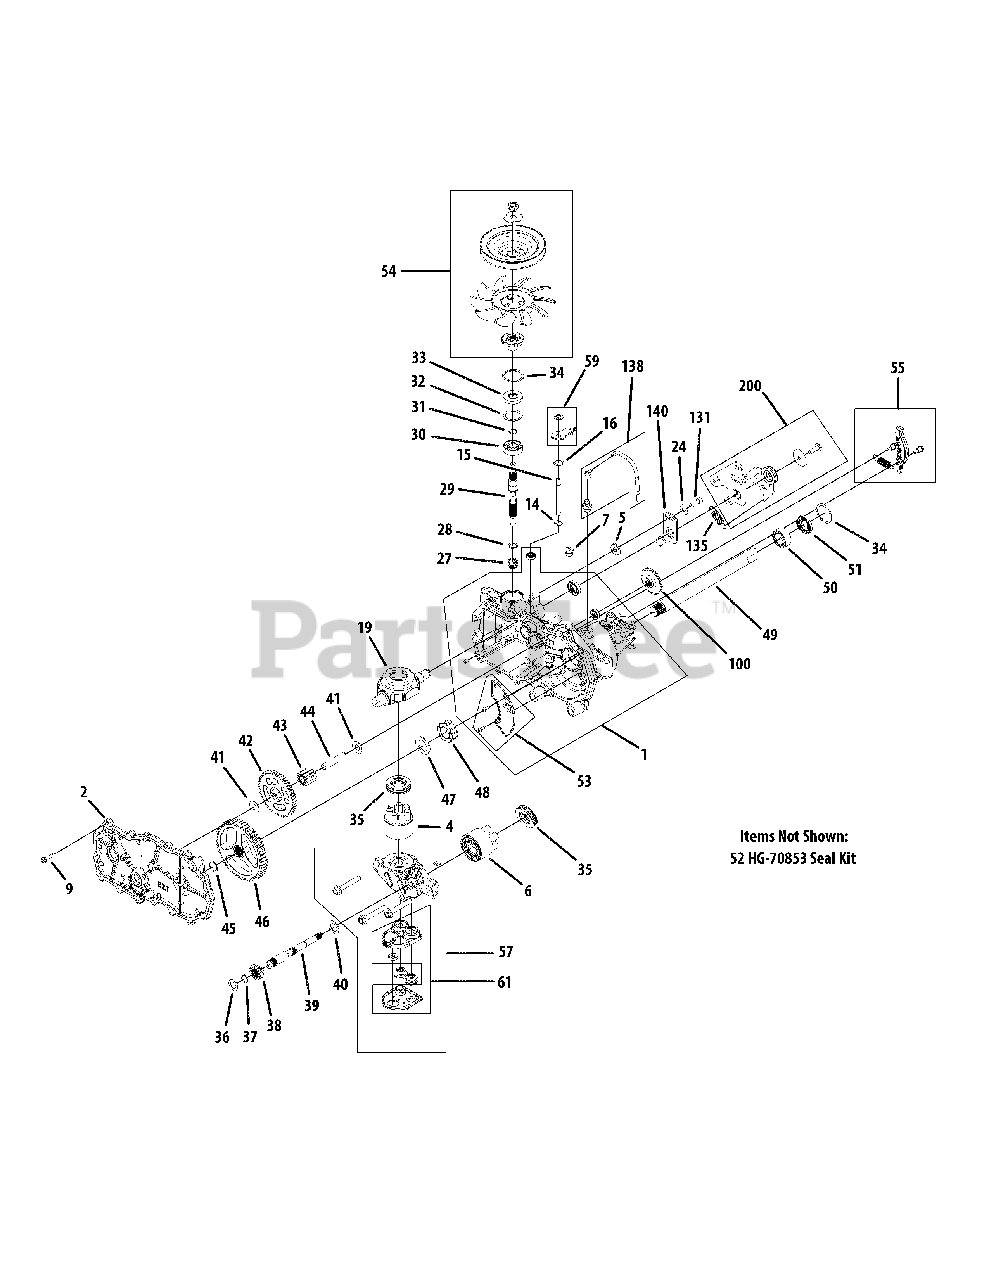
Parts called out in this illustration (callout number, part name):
1	Kit, Housing, Main, RH
2	Kit, Housing, Side, RH
4	Kit, Block, 7 Piston
5	Spacer, .320 x 1.005 x .150
6	Kit, Block, 10cc Cylinder
9	Screw, Hex Washer
14	Ring, Retaining .375 External
15	Rod, Bypass
16	Ring, Ret .375 External
19	Trunnion, Swashplate
24	Washer, .34 x .88 x .06
27	Spring, Block
28	Washer, .59 x .79 x .04
29	Shaft, Input
30	Ball Bearing 17 x 40 x 12
31	Ring, Reatining
32	Washer, 1.23 x 1.57 x .04
33	Seal, Lip 17 x 40 x 7
34	Ring Retaining Internal
35	Thrust Bearing, 30 x 52 x 13
36	Washer, .63 x 1.00 x .05
37	Ring, Reatining, Motor Shaft
38	Gear, 13T Pinion
39	Shaft, Motor
40	Washer, .71 x 1.16 x .04
42	Gear, 10T/48T
43	Gear, 10T Jackshaft
44	Pin, Jackshaft
45	Ring, Spiral Retaining-87
46	Gear, Bull 52T
47	Washer, 1.018 x 1.571 x .105
48	Buahing, Sleeve (Inboard)
49	Shaft, Axle, 1.00 x 11.70 DD
50	Bushing, 1.003 x 1.571 x .625
51	Seal, Lip, TC4, 1.00 x 1.577 x .27
52	Kit, Seals & Rings
53	Kit, Expansion Plate RH
54	Kit, Fan & Pulley
55	Kit, Brake Arm
57	Kit, Center Section RH
59	Kit, Bypass Arm
61	Kit, Filter
100	Disc, Cog Brake
131	Socket Cap Screw, 5/16-24 x 7/8
135	Spring, Extension
138	Kit, Breather
140	Arm, Neutral Right
200	Kit, RTN Bidirectional
